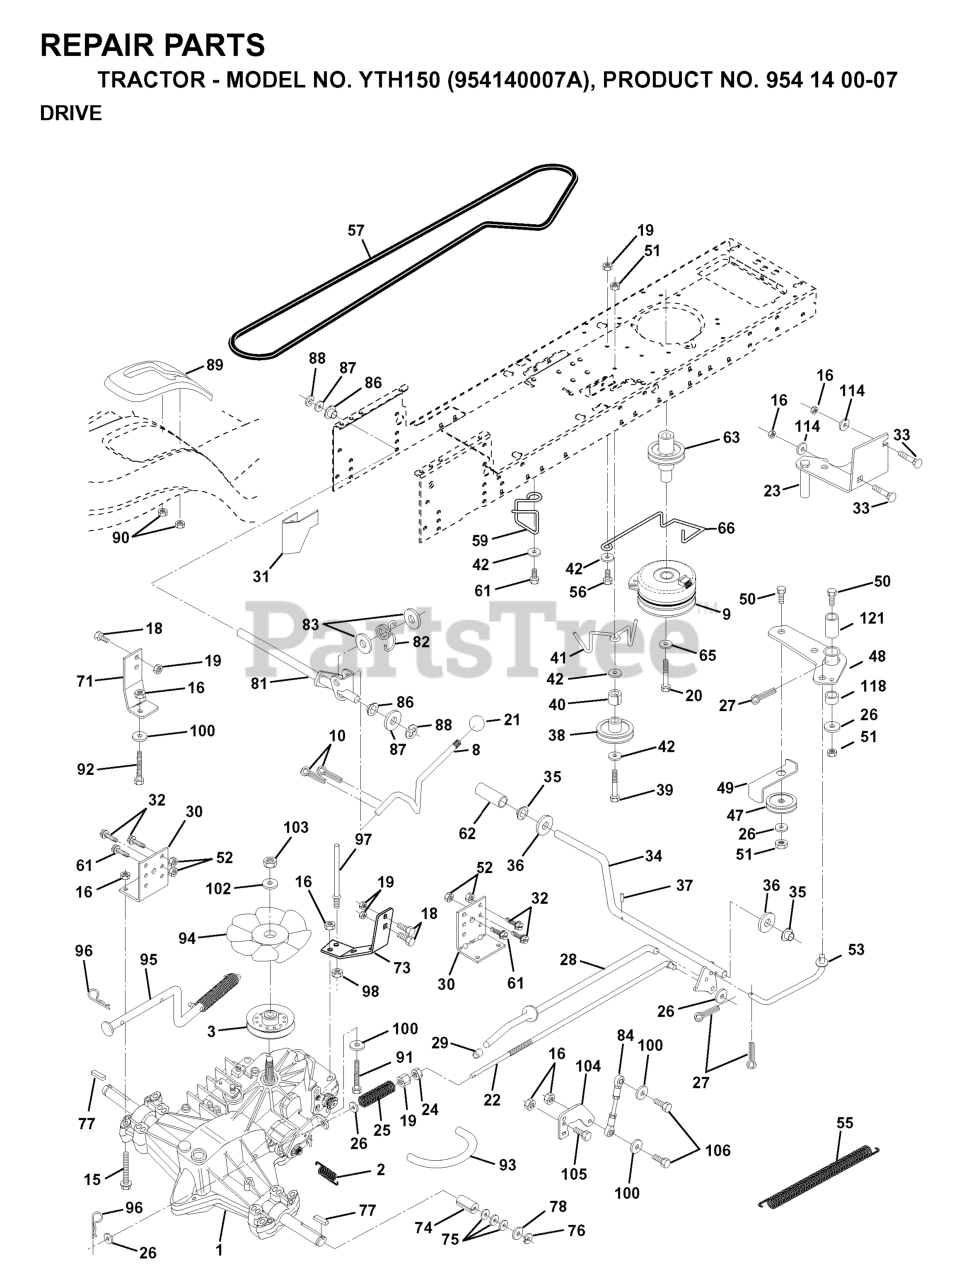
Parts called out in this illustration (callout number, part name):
1	TRANSAXLE ASSEMBLY
2	SPRING BRAKE
3	PULLEY, TRANSAXLE
8	ROD SHIFT FENDER
9	CLUTCH.ELECT.EVX.
10	PIN COTTER
15	BOLT HEX 5/16-18 GR 5
16	NUT.71038.31-18.HEX.NYLOCK
19	NUT
20	BOLT HEX
21	KNOB.DELUXE.(PISTOL.GRIP).BLAC
22	ROD BRAKE HYDRO
23	BRACKET, ASM CLUTCH MTG
24	NUT
25	SPRING ROD LT
26	WASHER
27	COTTER PIN
28	ROD BRAKE PARK LT
29	PLUNGER CAP
30	BRACKET TRANSAXLE
31	KEEPER BELT LH
32	BOLT
33	RP BOLT 5/16-18 X3/4 ZN/YEL GR
34	SHAFT, FOOT PEDAL
35	BEARING.NYLON
37	DRIVE PIN
38	PULLEY.IDLER.FLAT
41	KEEPER, BELT IDLER
42	WASHER
47	IDLER PULLEY
48	BELLCRANK ASSEMBLY
49	RETAIN BELT
50	BOLT
52	LOCKNUT
53	LINK, CLUTCH LT
55	SPRING, RETURN LT
57	DRIVE BELT, LTH & YTH TRACTORS
59	KEEPER CENTER SPAN
61	SCREW
62	COVER, PEDAL (1 2)
63	PULLEY, CLUTCH ELECT EVX
65	LOCKWASHER
66	KEEPER BELT ENGINE
71	STRAP LH TORQUE
73	STRAP TORQUE RH HYDRO
74	SPACER SPLIT
77	SQUARE KEY
81	SHAFT ASSY
82	SPRING,TORSION
83	WASHER
84	ROD.TIE.BALL.4.75
86	BUSHING.STEERING.ROD LTB-WSL
89	CONSOLE SHIFT
90	NUT.PUSH.3/16
91	BOLT.FIN HEX 5/16-18UNC X2 1/4
92	HEX BOLT
93	LINE FUEL HYD 4"
94	FAN 7" HYDRO
95	CONTROL ARM, BYPASS HYDRO
96	RETAINER M
97	KEEPER BELT RH
100	WASHER M
103	NUT.HEX.1/2-20
104	CONTROL ARM
106	BOLT.5/16-18X1-1/4 FULL.THREAD
114	Washer 11/32 x 3/4 x 14 Gauge
118	SPACER BELLCRANK
121	NYLINER CLUTCHING
